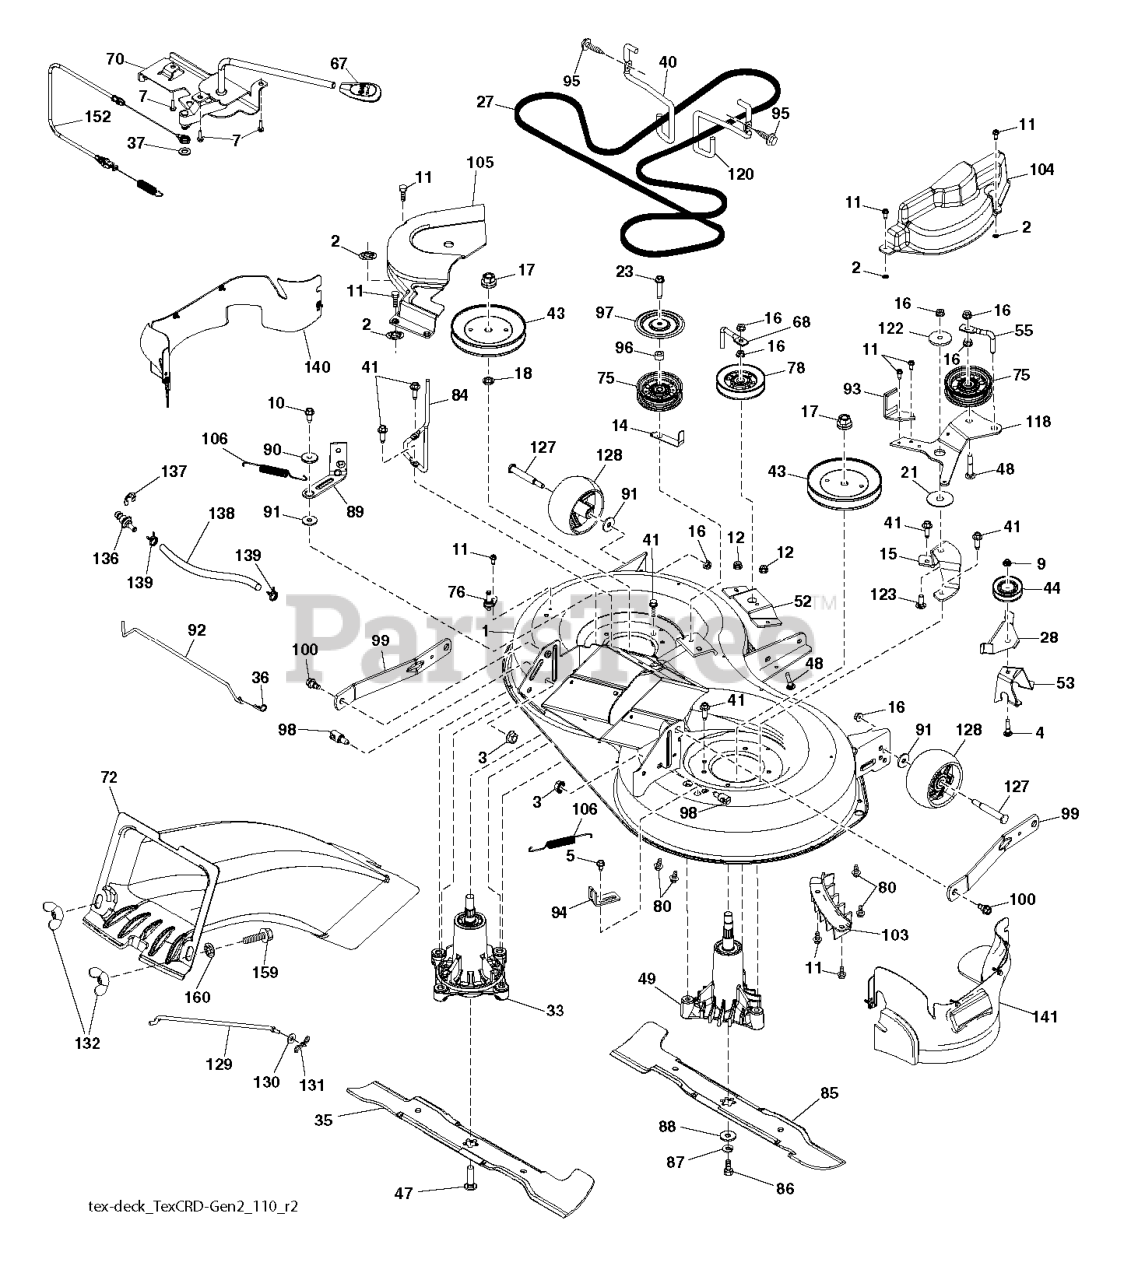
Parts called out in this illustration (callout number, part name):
1	KIT.SVC.DECK.WLD.97CM.TEX.498
2	PALNUT 1/4
4	BOLT.CARRIAGE.5/16-18
5	BOLT.5/16HEX.WHS.HD
9	NUT HEX FLG NYLOCK BLK 5_16-1
10	SCREW 3/8-16X1
11	SCREW.1/4-20X5/8
14	KEEPER, BELT IDLER
15	BRACKET CRD IDLER ARM MOUNT BL
16	NUT LOCK FLG 3/8-16 UNC
18	WASHER.SPACER.MANDREL
23	BOLT;HEX_3/8-16 X 1.78.CLRZINC
28	KEEPER 97 CRD ANGLED IDLER KEE
33	KIT.MANDREL.NONGREASE.TALL
35	BLADE.3N1.LH.CRD.97
36	RETAINER M
37	WASHER PLAIN WASHER 3/8 X 0.08
40	KEEPER BELT ENGINE LH
41	BOLT.HEX.WASHR.HED.313-18X1.19
43	PULLEY.MANDREL.5.438.PD
44	PULLEY.V-IDLER.
47	SCREW.SEMS.7/16-20X1.HEX.HEAD
49	MANDREL ASM.CRD RH 6PT STAR
53	BRACKET 97 CRD ANGLED V-IDLER
67	HANDLE.CLUTCH.CABLE.LT
70	CLUTCH.ASM.MANUAL.LT.PRED
72	CHUTE.TEX.CRD.GEN I.97 UPPER
76	1/2" BARB.DECK.WASHOUT.PORT
78	REPL BY 532 1467-63
80	GSPW Bolts
84	KEEPER.BLT.PNT.MNDRL.PULL.6.25
85	BLADE.3N1.RH.CRD.97
86	BOLT.3/8-24X1.25GR8. LHTHRD
88	WASHER.BLADE
89	ARM.BRAKE.97.LH
90	SPACER.RETAINER
92	LINK 97 CRD MANUAL DRIVE BRAKE
93	BRAKE CRD RH BRAKE ARM BLACK E
94	BRKT.CLUTCH.CABLE
95	SCREW, 3/8-16X3/4
96	SPACER
97	PROTECTOR
98	STUD.W/"D"ANTI-ROTATION
99	ARM.SUSPENSION.MOWER.R
100	BOLT.SHOULDER
103	GUARD GUARD FRONT VENT
104	GUARD 97CRD RH MANDREL COVER;
105	MANDREL MANDREL COVER LH
106	SPRING.BRAKE.RETURN.38"
120	KEEPER BELT RH
122	SPACER.RETAINER.MOWER
128	WHEEL.GAUGE.RALLY
129	ROD.ANTI.SWAY.48/54"K4
131	PIN.COTTER.5/16.BOW TI
132	KNOB.HANDLE.3/8.TRI-POINT.BLAC
136	PLUG WASHOUT PORT HOOKUP
138	HOSE.3/8ID.BULK.12"
140	GUARD.ASSEMBLY.97.LH.FRENCH
141	GUARD.ASSEMBLY.97.RH.FRENCH
152	CABLE CABLE CLUTCH MANUAL W/S
